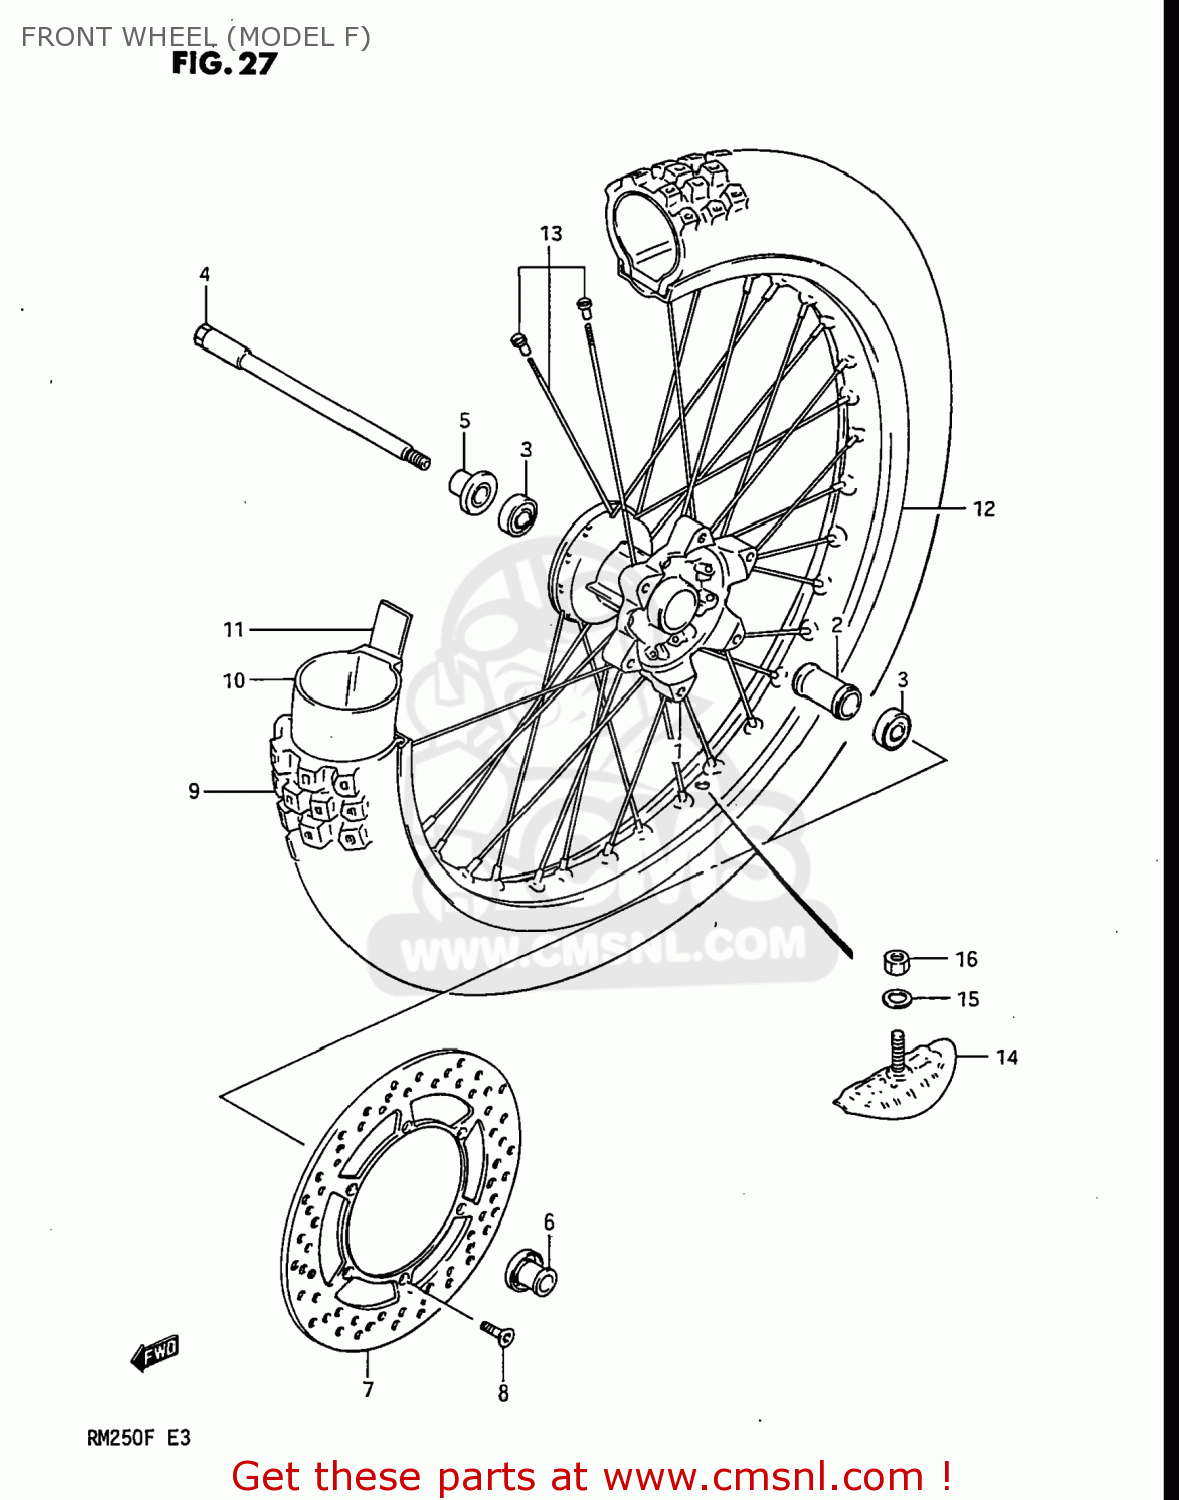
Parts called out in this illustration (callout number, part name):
1	HUB,FRONT
2	SPACER,FRONT HUB BEARING
3	BEARING
4	AXLE,FRONT
5	SPACER,FRONT AXLE,RIGHT
6	SPACER,FRONT AXLE,LEFT
7	DISC,BRAKE
8	SCREW
9	TIRE,FRONT
10	TUBE
11	PROTECTOR,WHEEL,INNER
12	RIM,FRONT WHEEL (1.60X21)(
13	SPOKE SET,FRONT
14	STOPPER,BEAD
15	WASHER
16	NUT
